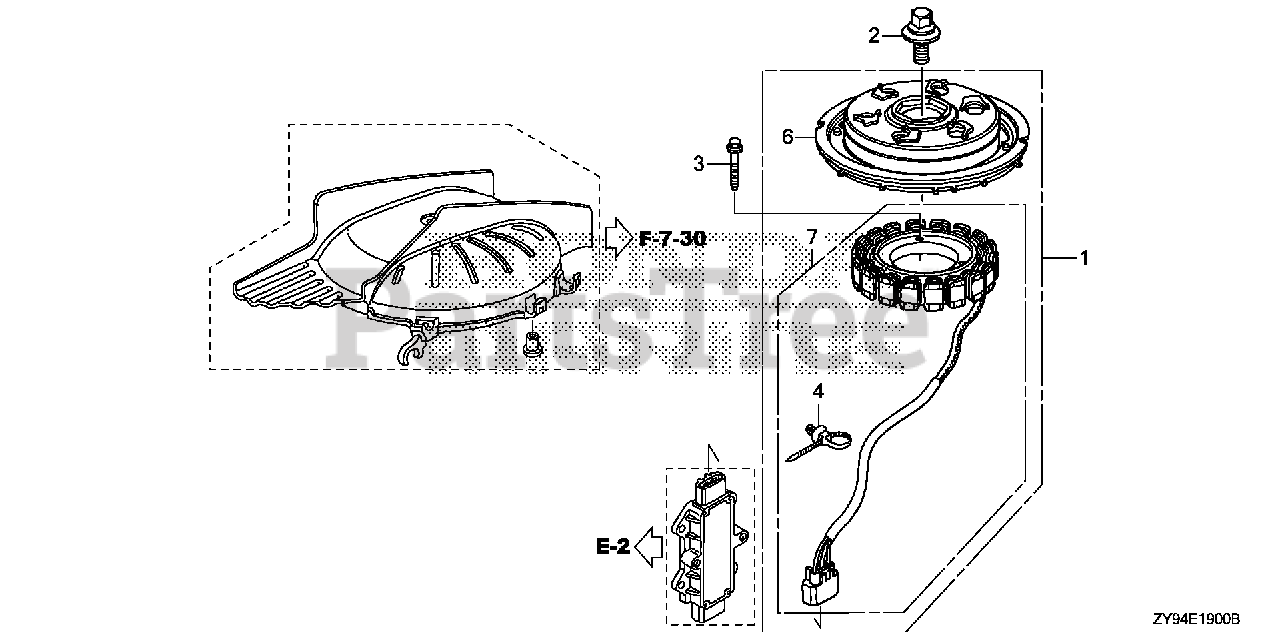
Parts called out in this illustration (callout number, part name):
1	ALTERNATOR ASSY.
2	BOLT-WASHER (14X36)
3	BOLT, FLANGE (6X32) (CT200)
4	CLIP, HARNESS BAND (96.9MM) (NATURAL)
